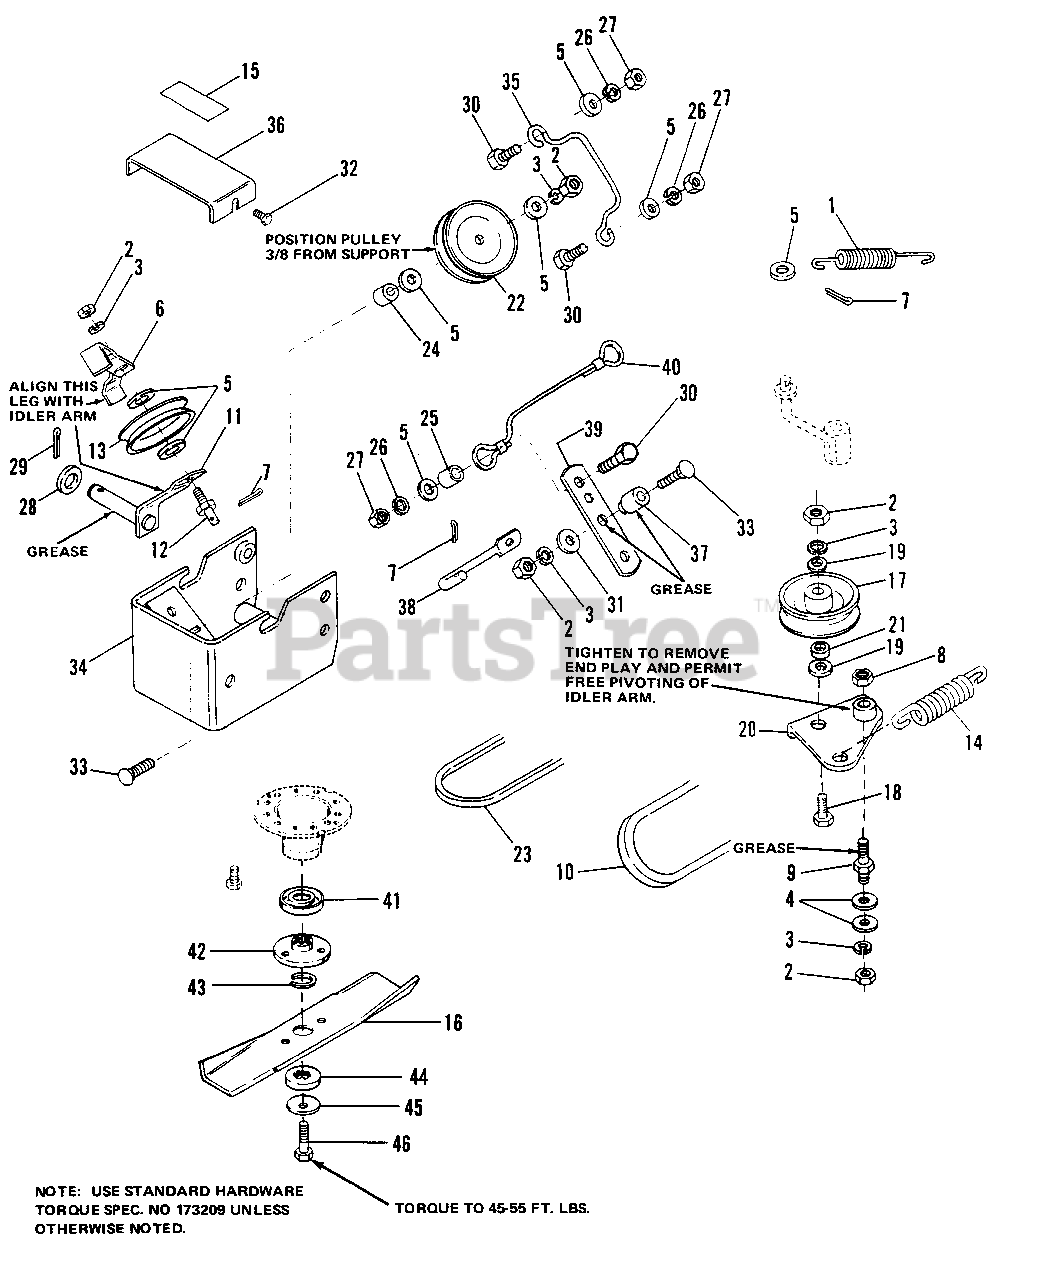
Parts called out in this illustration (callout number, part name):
2	NUT, Hex, 3/8-16
3	LOCKWASHER, 3/8-16
4	WASHER, 3/8
5	WASHER, 5/16
6	GUIDE ASSY., Belt
7	PIN, Cotter, 3/32 x 3/4
8	LOCKNUT, Hex, 3/8-16
9	STUD, Idler
10	"V" BELT, Arbor Drive
11	LEVER ASSY., Idler
13	PULLEY, Idler
15	DECAL, Caution
16	BLADE, 42" Mower
17	PULLEY, Idler
18	CAPSCREW, Hex 3/8-16 x 1-3/4
19	WASHER, 13/32 x 7/8
20	LEVER ASSY., Idler
22	PULLEY, Idler
23	"V" BELT, PTO
26	LOCKWASHER, 5/16
27	NUT, 5/16-18
28	WASHER, 7/16
29	PIN, Cotter, 3/32 x 1
30	CAPSCREW, Hex 5/16-18 x 1
31	WASHER, 13/32 x 1
32	SCREW, Tap, 1/4-20 x 3/8
33	BOLT Carriage, 3/8-16 x 1-1/2
34	SUPPORT ASSY., Mower
35	STOP, Belt
36	COVER, Pulley
38	ROD, Clutch
39	BELLCRANK
40	CABLE ASSY., Brake
41	SHIELD, Grass
42	ADAPTOR, Blade
43	RING, Self Locking
44	WASHER, Spline
45	WASHER, Spline
46	CAPSCREW, Hex Hd., 7/16-14 x 1
